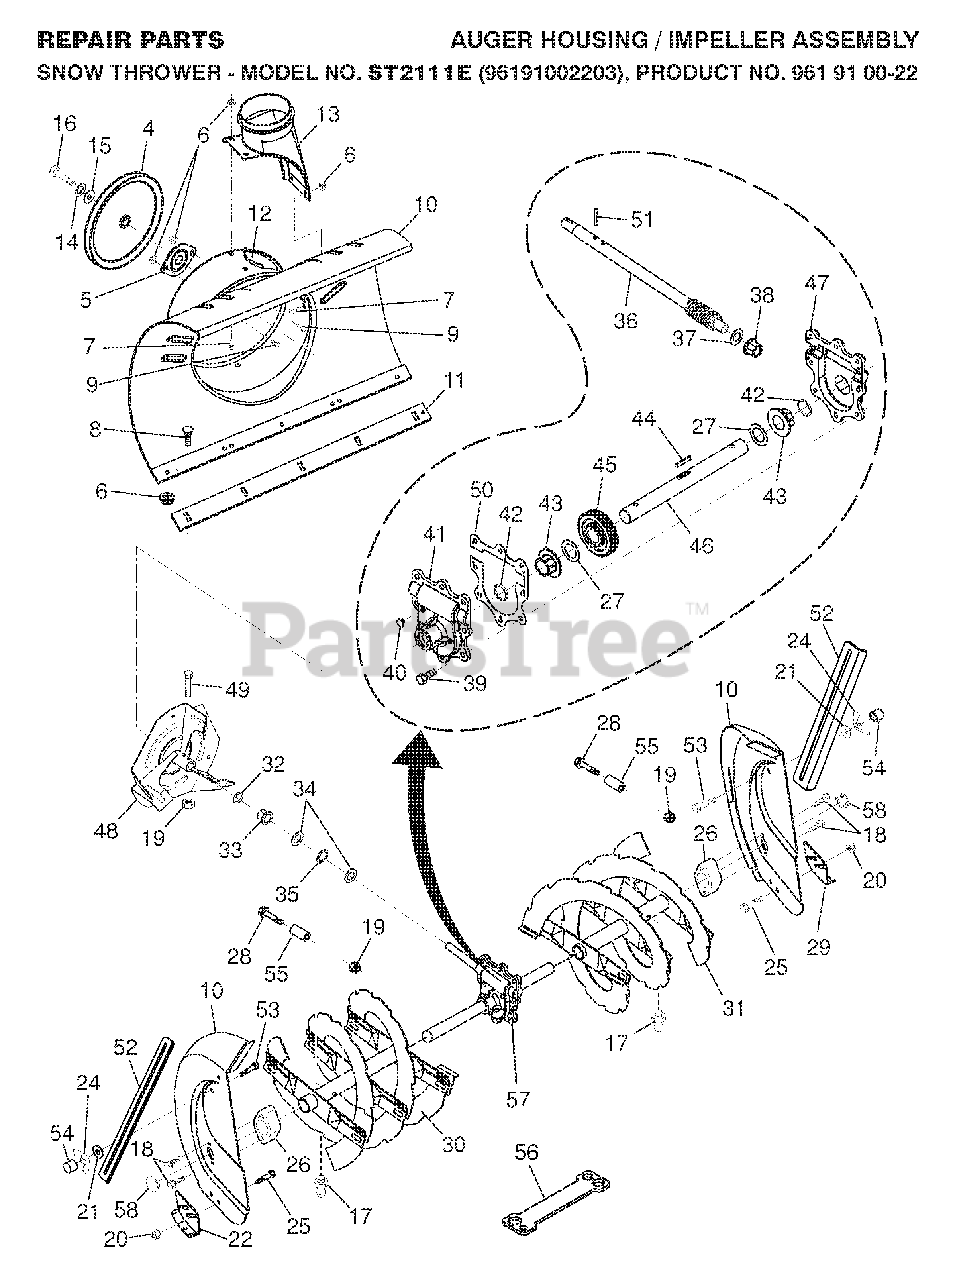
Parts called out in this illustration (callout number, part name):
1	WEIGHT AUGER HOUSING 30
2	NUT, LOCK 5/16-18
3	BOLT.CARRIAGE.5/16-18
4	PULLEY, IMPELLER
5	BEARING FLANGE
6	NUT.FLANGE.5/16
7	BOLT.CARRIAGE.5/16-18X
8	BOLT
9	BOLT, HEX HEAD 5/16-18
11	RP BAR.SCRAPER.30.BLACK
12	BRACKET, CORNER DISCHARGE
13	BASE DISCHARGE CHUTE
14	LOCKWASHER
15	WASHER, FLAT
16	CAPSCREW.HX.HD.5/16-18X1.00.NY
17	GREASE FITTING
18	SCREW, HEX HD 5/16X1
19	LOCKNUT
20	NUT.FLANGE.5/16
21	WASHER, FLAT 5/16
22	SKID PLATE RH
24	NUT WING PM
26	BEARING RETAINER, PLASTIC
27	WASHER TRUST 1"
28	BOLT, SHEAR
29	SKID PLATE LH
30	RP AUGER ASSEMBLY, RH
31	RP AUGER ASSEMBLY, LH
33	BUSHING, FLANGE 3/4
34	WASHER, THRUST 3/4
35	BEARING TRUST 3/4
36	SHAFT, IMPELLER
37	WASHER, THRUST 5/8
38	FLANGE BUSHING-5/8
39	HEX SCREW-5/16 X 3/4
40	CASE PLUG
41	GEARBOX HOUSING-RH
42	OIL SEAL
43	FLANGE BUSHING-1"
44	KEY, SQUARE 1/4 X .875
45	WORM GEAR
46	AUGER SHAFT
47	GEARBOX HOUSING - LH
48	IMPELLER ASSY
49	SCREW.HEX.HD1/4-20X
50	GEARBOX GASKET
51	PIN, ROLL 3/16 X 1-1/8
52	DRIFT CUTTER BAR
54	STOP.11261.PLASTIC.30X50L.RED
56	RP WRENCH, SNOWTHROWER
57	GEARBOX.ASSEMBLY.AUGER
58	BEARING.BALL.AUGER.SHAFT
